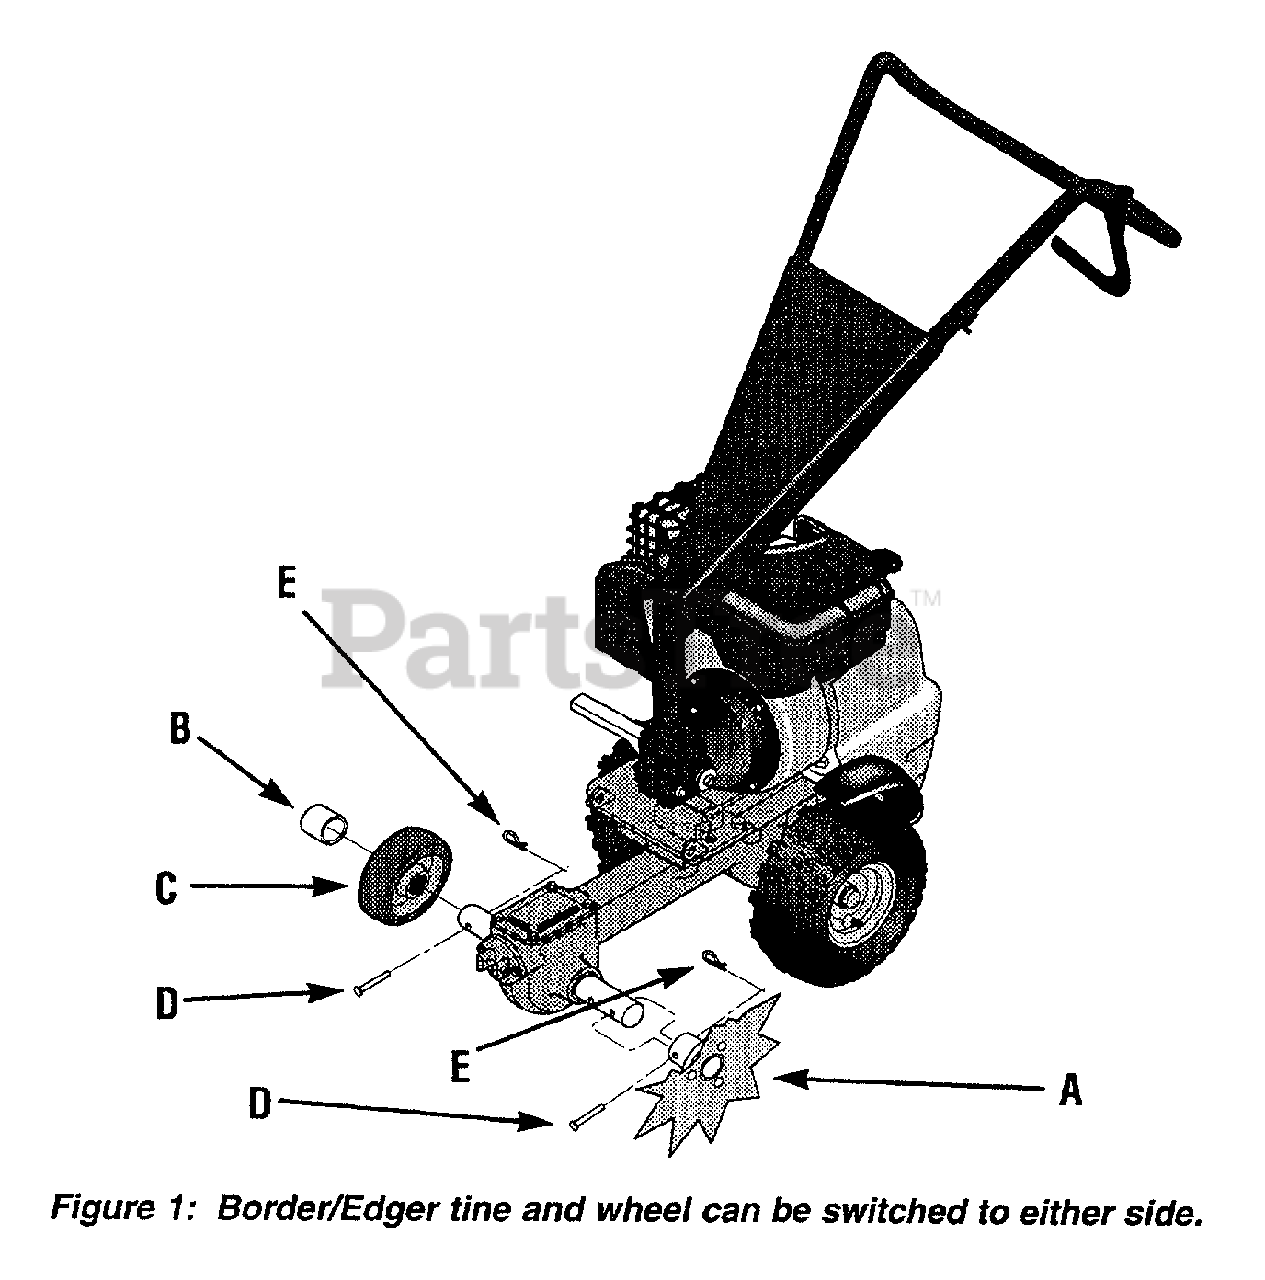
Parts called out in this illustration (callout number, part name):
A	Border Edger Tine
B	Wheel Spacer
D	Clevis Pin
E	Hair Pin Clip
